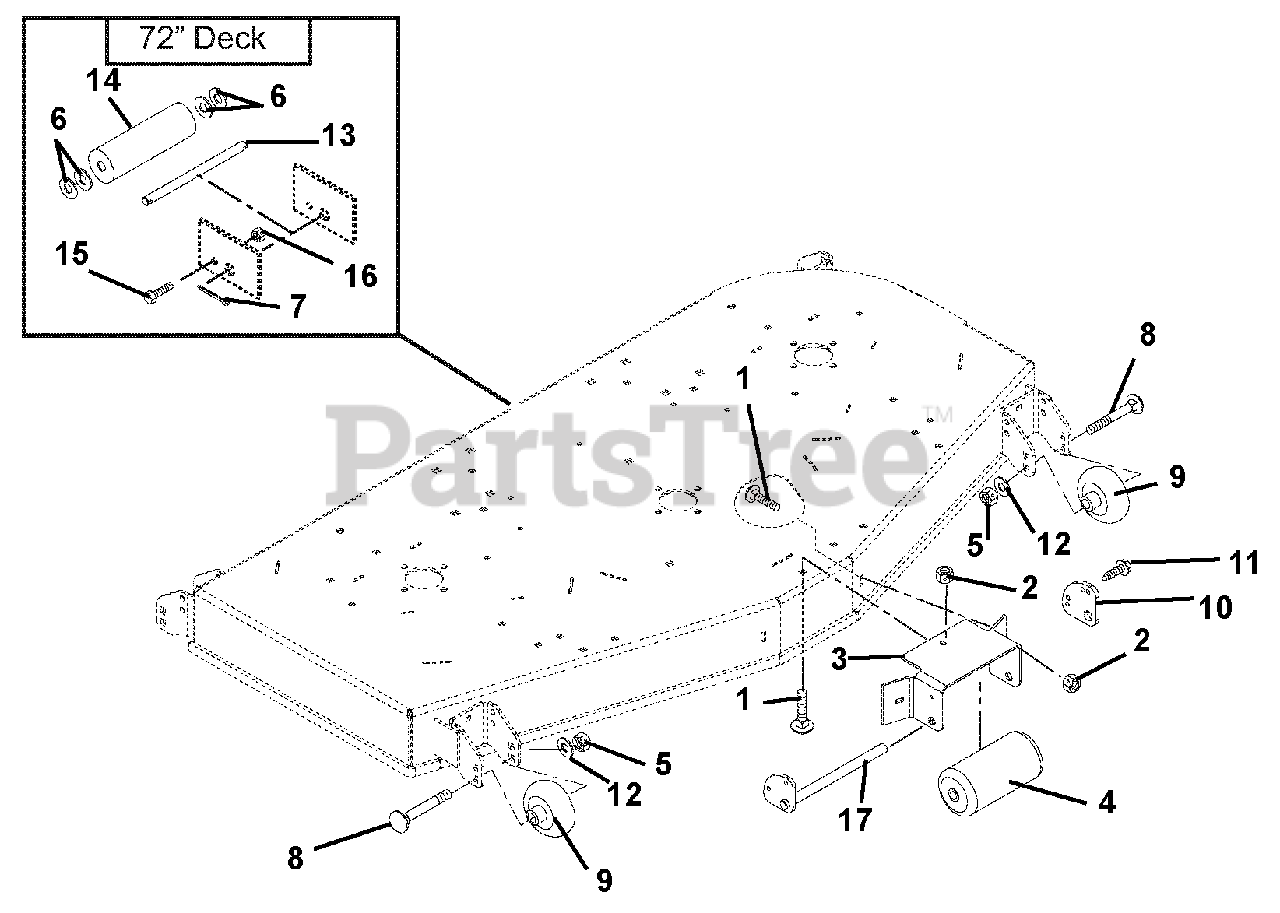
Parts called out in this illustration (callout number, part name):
1	@BLT-RDHDSQNK .38-16X1.00 G5YZ
2	@NUT-LK-TOP-FLG .38-16 YWZC
3	BRACKET - ANTI-SCALP ROLLER
5	@NUT-LK-NYL .50-13 YWZC
6	@WSHR-FL-STL.656X1.31X.095 YWZ
7	@PIN-CTR .25X2.00 YWZC
8	BLT-RDHDSQNK .50-13X5.00 GR5YZ
9	WHEEL, 3X5
10	ANTI-SCALP WASHER - RED
11	SCR-TAP.250-20X.62 HWH BLK ZC
12	@WSHR-FL-STL.531X1.06X.095YWZC
13	SHAFT,CENTER ROLLER
14	RLR,GAGE
15	@BLT-HEX .25-20X.75 GR5 YWZC
16	@NUT-LK-CTR .25-20 YWZC
17	WMT - ROLLER BRACKET
